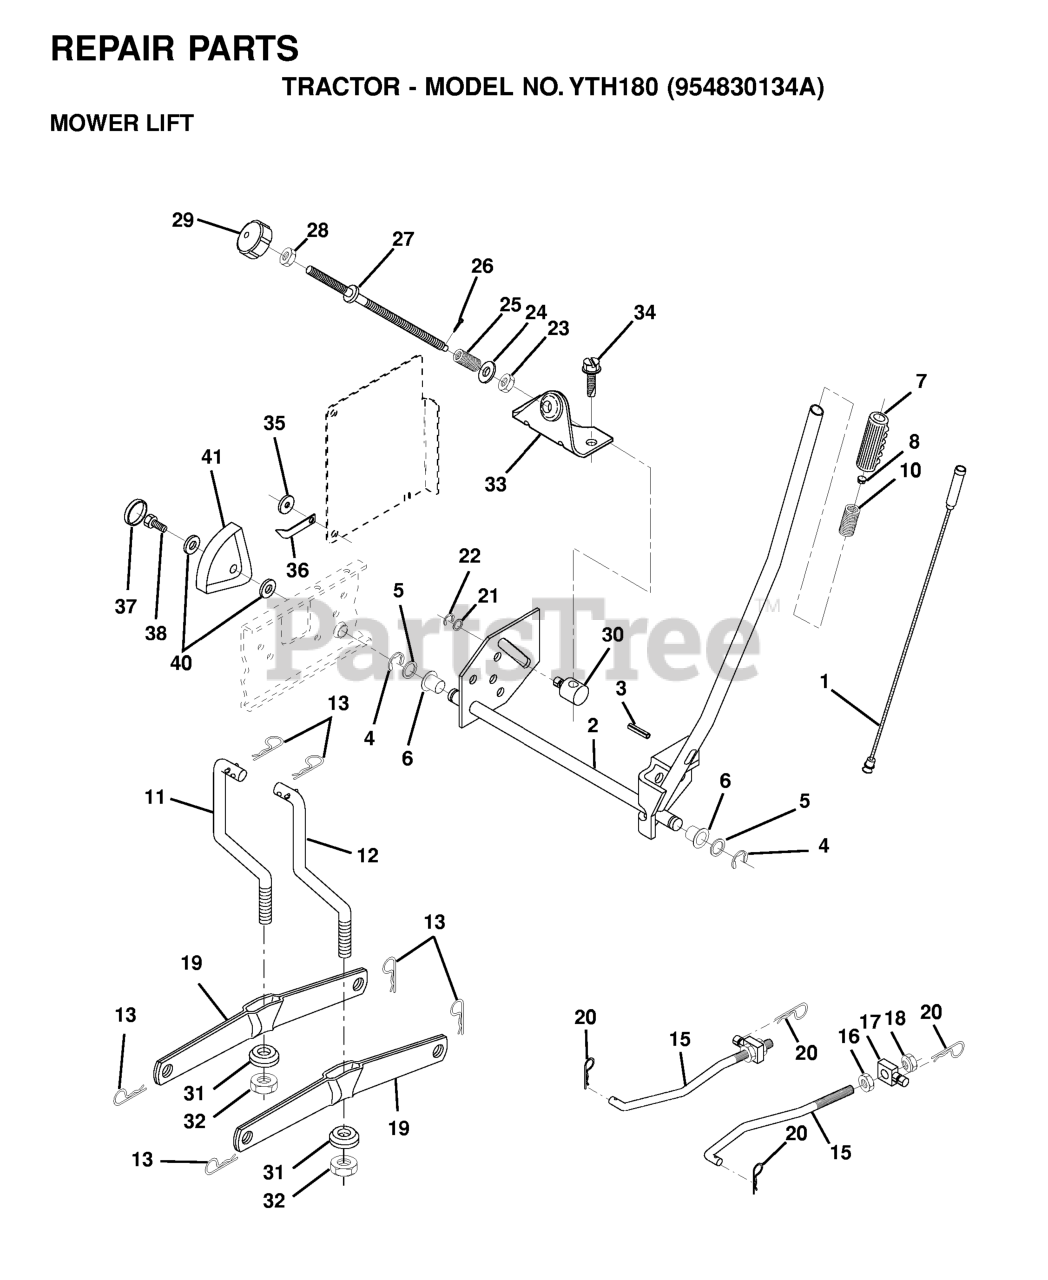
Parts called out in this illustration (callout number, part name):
1	WIRE.INNER.HANDLE.LIFT.LEVER
2	SHAFT ARM LIFT RH
3	PIN GROOVE.
4	RETAINING RING LT
6	BEARING.NYLON
7	GRIP HANDLE
8	PLUNGER BUT KIT
10	SPRING, COMP T
11	LINK LIFT LH
12	LINK LIFT RH
13	RETAINER-SPRNG RB
15	FRONT LINK
16	NUT.HEX.JAM.1/2-13
17	TRUNION
18	NUT.LK.W/WSH.1/2.
19	ARM.REAR.SUSPENSION
20	SPRING RETAINER
21	Washer 15/32 x 3/4 x 16 Gauge
22	Ring, Klip #T5304-37
25	SPRING**
26	COTTER PIN
27	ROD ADJ LIFT
28	NUT
29	KNOB INF 3/8-16
30	TRUNION LT
31	BEARING PIVOT
32	NUT CROWNLOCK 3/8-24
36	HEIGHT INDICATOR PNTR
38	SCREW.THDROL.5/16-18X3/4.TTY
41	HEIGHT INDICATOR
